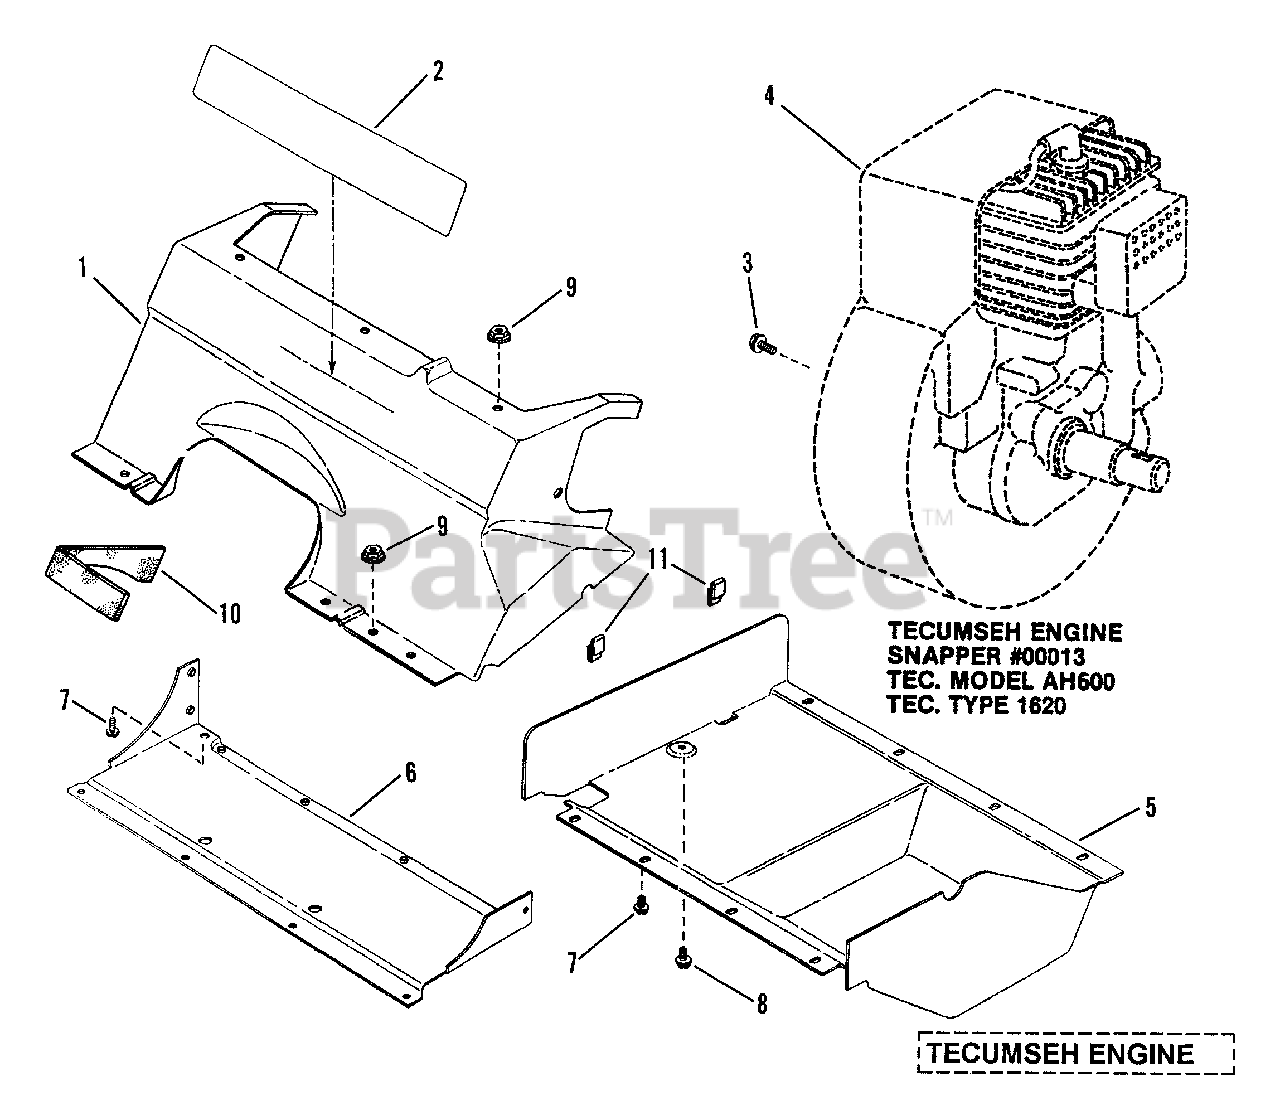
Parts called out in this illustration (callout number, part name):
1	COVER, Top
2	DECAL, Snapper
3	BOLT, 1/4-20 x 3/8" Hex Flange Lock, Grade 5
5	COVER, Bottom
6	BLADE
7	SCREW, #10-24 x 1/4" Hex Washer Self-Tap
8	SCREW, #10-24 x 1/2" Hex Washer Self-Tap
9	NUT, #10-24 Hex Flange Lock
10	SEAL, Foam
11	CLIP, "S"
